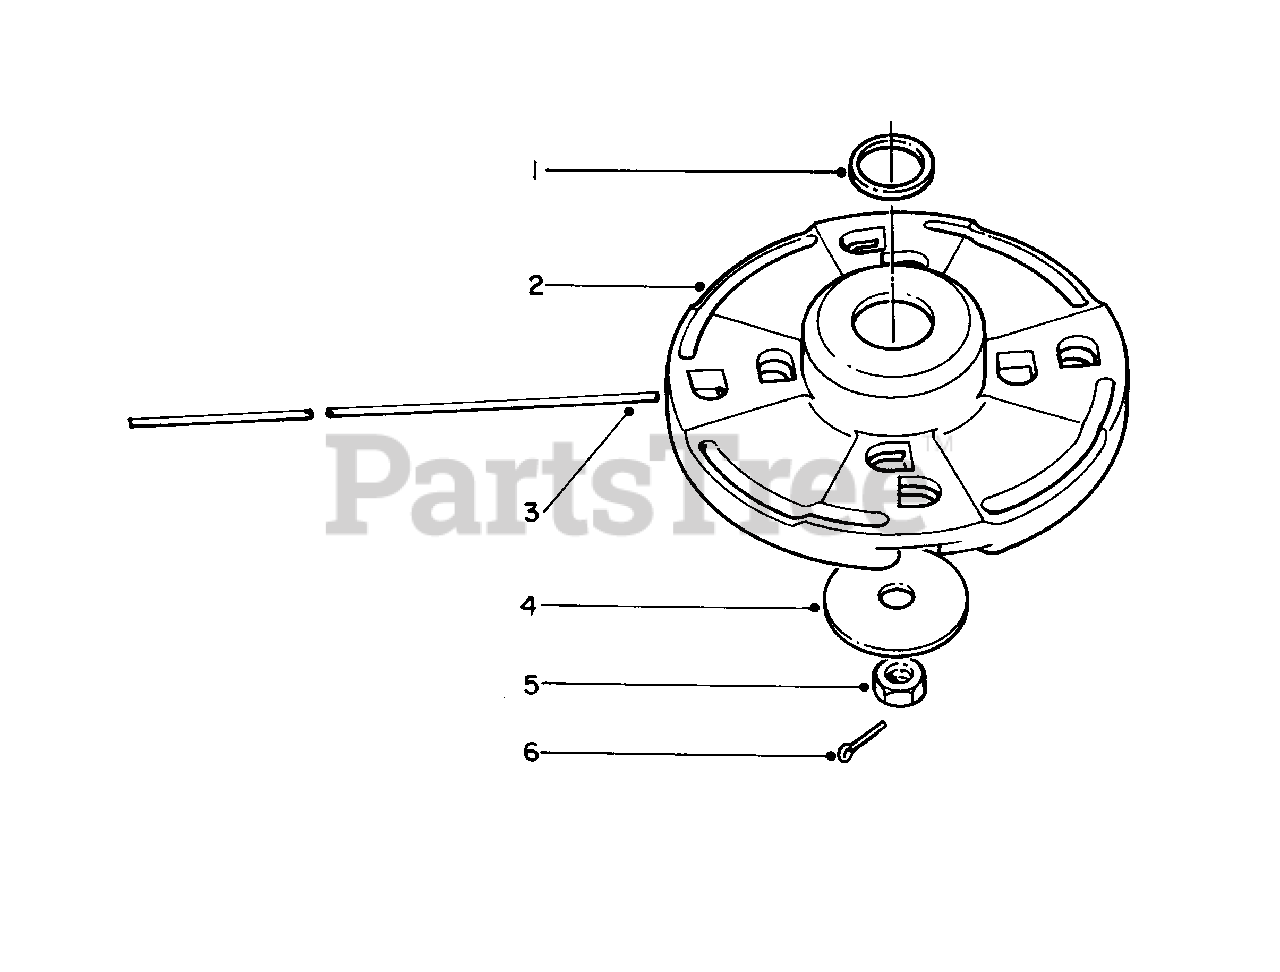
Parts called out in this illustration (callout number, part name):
2	Cutter Head (Incl. Ref. #1)
3	.105 Line (24 pcs.)(optional)
4	Washer Plate
6	Split Pin
